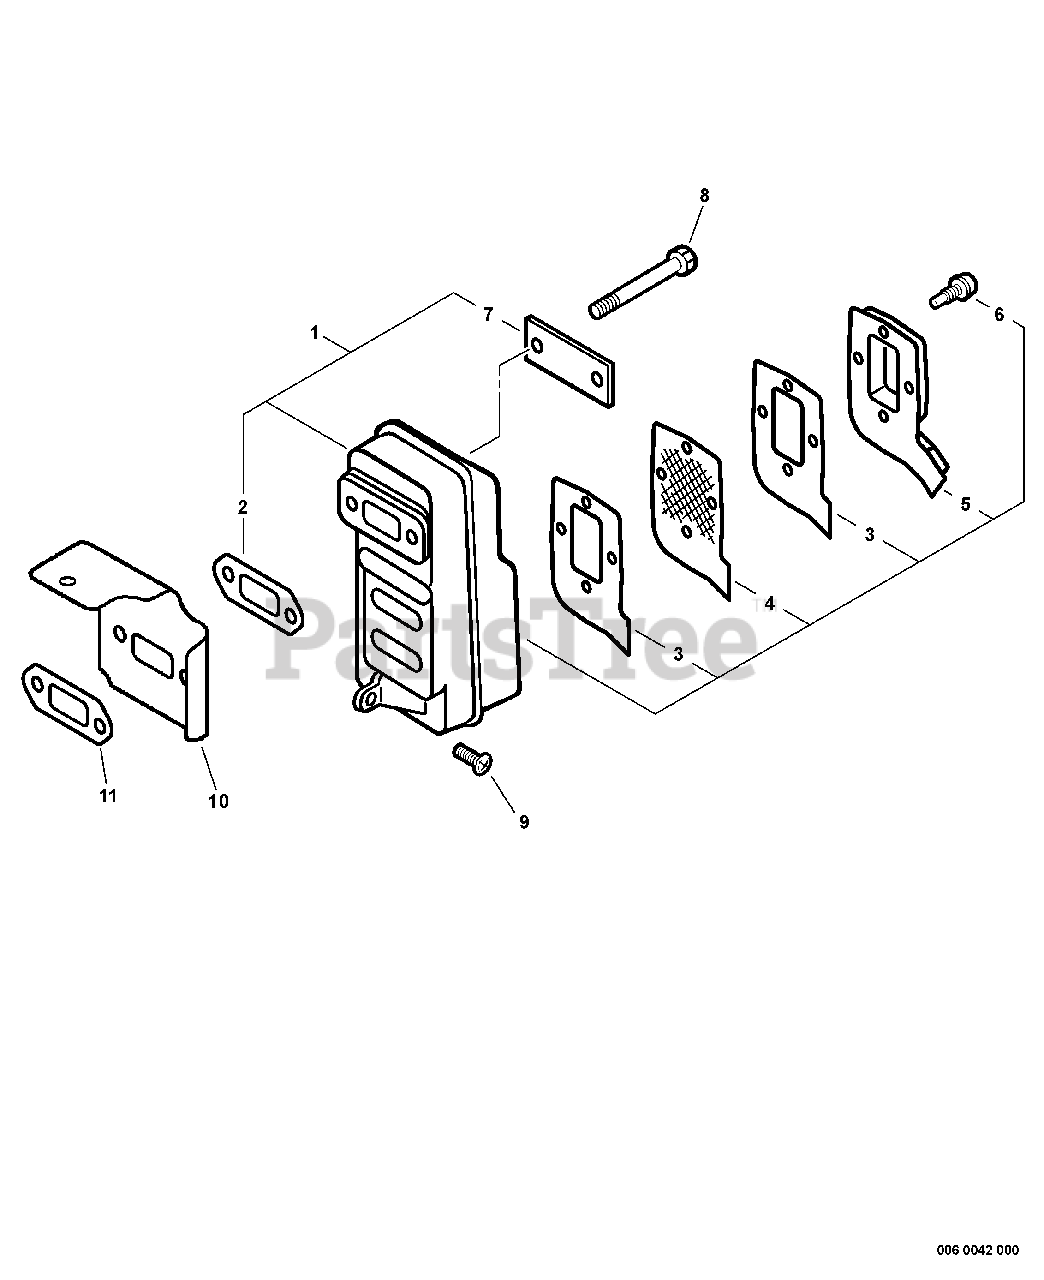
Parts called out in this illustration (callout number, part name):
1	MUFFLER ASSY
2	GASKET, EXHAUST
3	GASKET, EXHAUST
4	SCREEN, SPARK ARRESTOR
5	GUIDE, EXHAUST
6	SCREW - 4
7	PLATE
8	BOLT
9	SCREW - 5X20
10	COVER, CYLINDER
11	GASKET, EXHAUST
